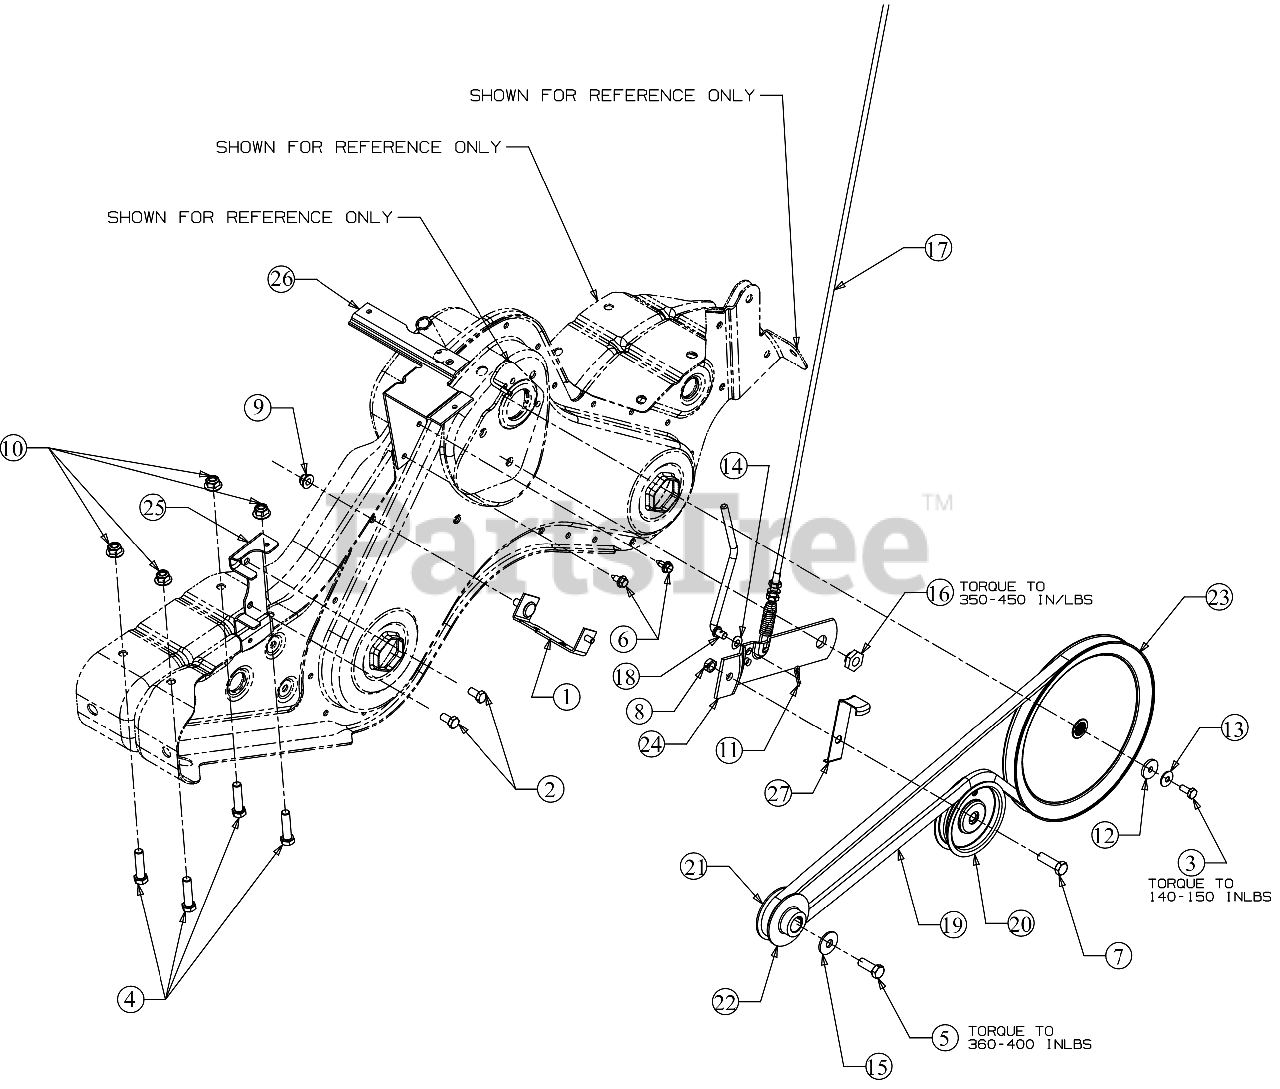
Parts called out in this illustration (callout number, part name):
1	BELT COVER BRACKET ASSEMBLY
1	WELD BOLT 5/16-18 X .875
2	HEX SCREW 5/16-24 X .62
3	BOLT 1/4-28 X .625 GR8
4	SCREW 3/8-16 X 1.50
5	SCREW 3/8-24 X 1.00 GR8
6	SCREW 1/4-20X.625
7	SCREW 3/8-16 X 1.25 GR5
8	JAM LOCK NUT
9	FLANGE LOCK NUT 5/16-18
11	COTTER PIN .072 DIA
12	FLAT WASHER
13	SPRING WASHER BELL
14	SPRING WASHER .317 X .625 X .020
15	BELL WASHER
16	SHOULDER NUT
17	CLUTCH CABLE
18	IDLER PULLEY ROD
19	BELT 1/2 X 58.16
20	IDLER PULLEY
21	ENGINE PULLEY INNER HALF
22	ENGINE PULLEY OUTER HALF
23	INPUT PULLEY
24	IDLER BRACKET
25	BELT KEEPER BRACKET
26	SHIFT COVER BRACKET
27	IDLER BELT KEEPER
